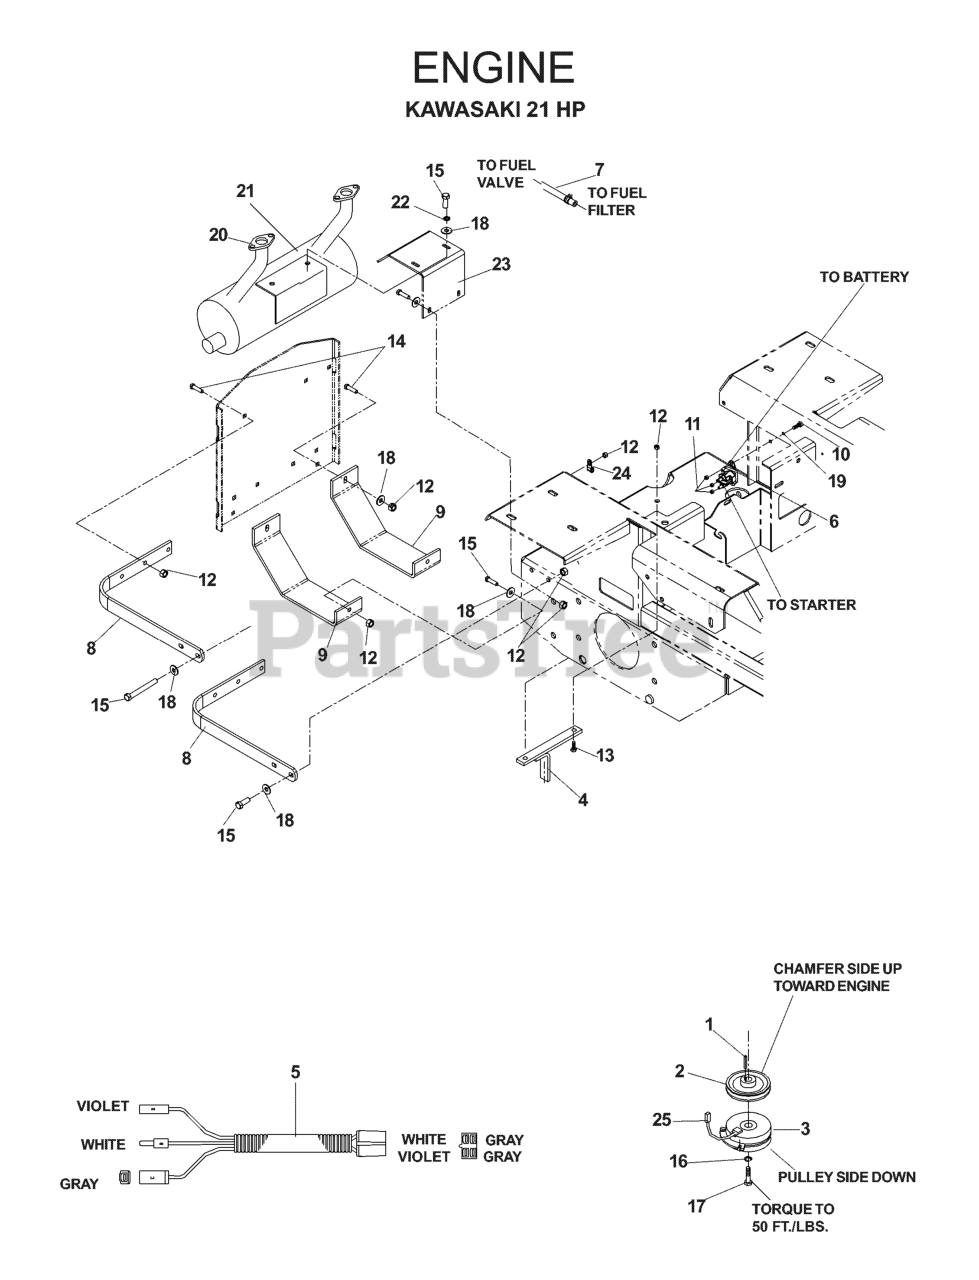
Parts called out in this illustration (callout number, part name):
1	KEY, 1/4 SQ X 1 1/4
3	CLUTCH-200 FT LB(RPLS 5218-102
4	CLUTCH TIE DOWN
5	KAW PIGTAIL
7	FUEL LINE 29.5"
8	ENGINE SHROUD BRKT
9	SKID PLATE
10	HCS 1/4C X 5/8
11	NUT.1/4-20.HEX.NYLOC.ZD
12	NUT 5/16 NYLOC
13	HCS 5/16C X 1 3/4
14	RHSSNB 5/16C X 1.0
15	HCS 5/16C X 1
16	WASHER 7/16 LOCK
17	BOLT 7/16F X 2 1/2
18	WASHER 5/16 FLAT
19	WASHER 1/4 INT TOOTH
20	EXHAUST GASKET - KAW
21	MUFFLER KAWASAKI GEN II
22	WASHER.LOCK.HVY.HLCL.SPR.5/16
23	MUFFLER BRACKET BLACK
24	DOUBLE TUBE CLAMP
25	CLUTCH HARNESS
